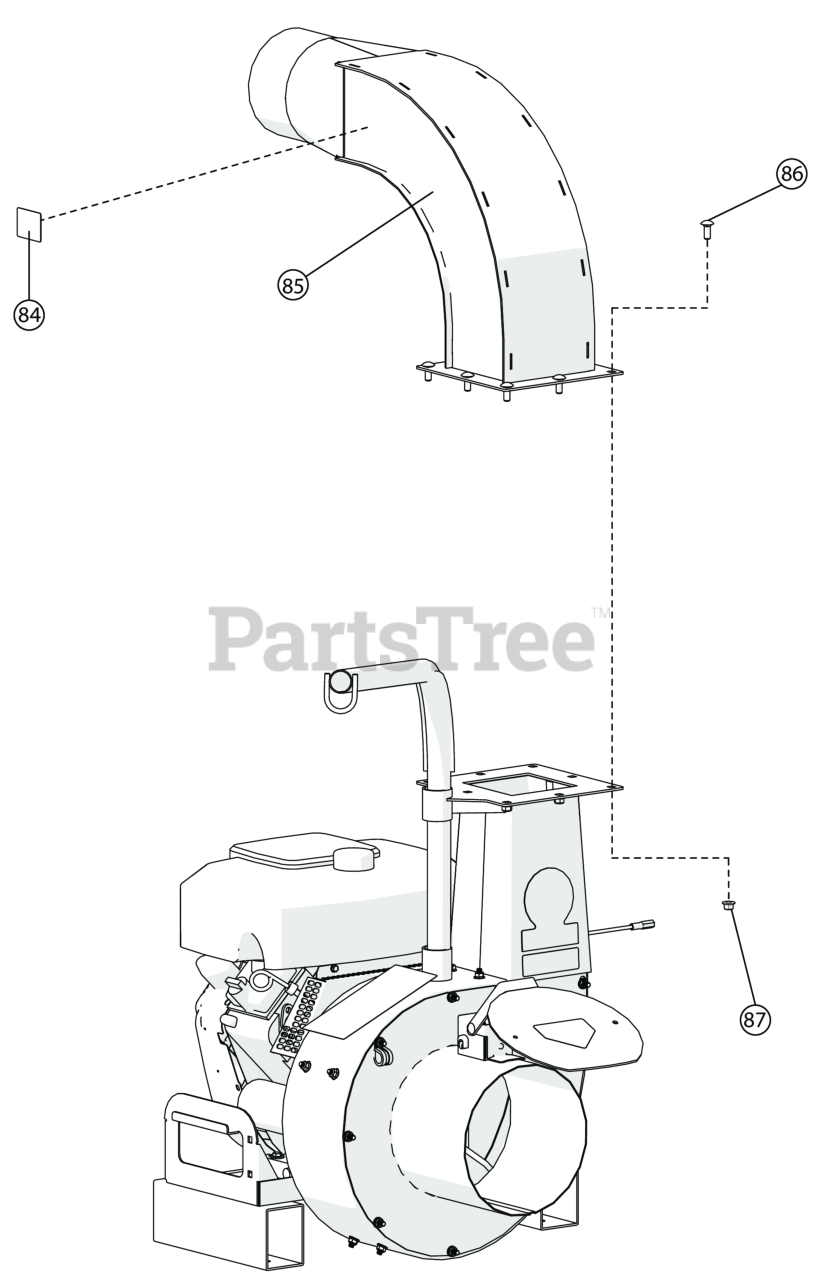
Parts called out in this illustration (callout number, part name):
84	LABEL DANGER FLYING DEBRIS
85	WA, ELBOW, 6" SQUARE, SQUARE FLANGE
86	BOLT CARRAIGE 3/8-16 X 1" ZP
87	NUT-HEX-NYLK, FLG .375"-16 ZP
